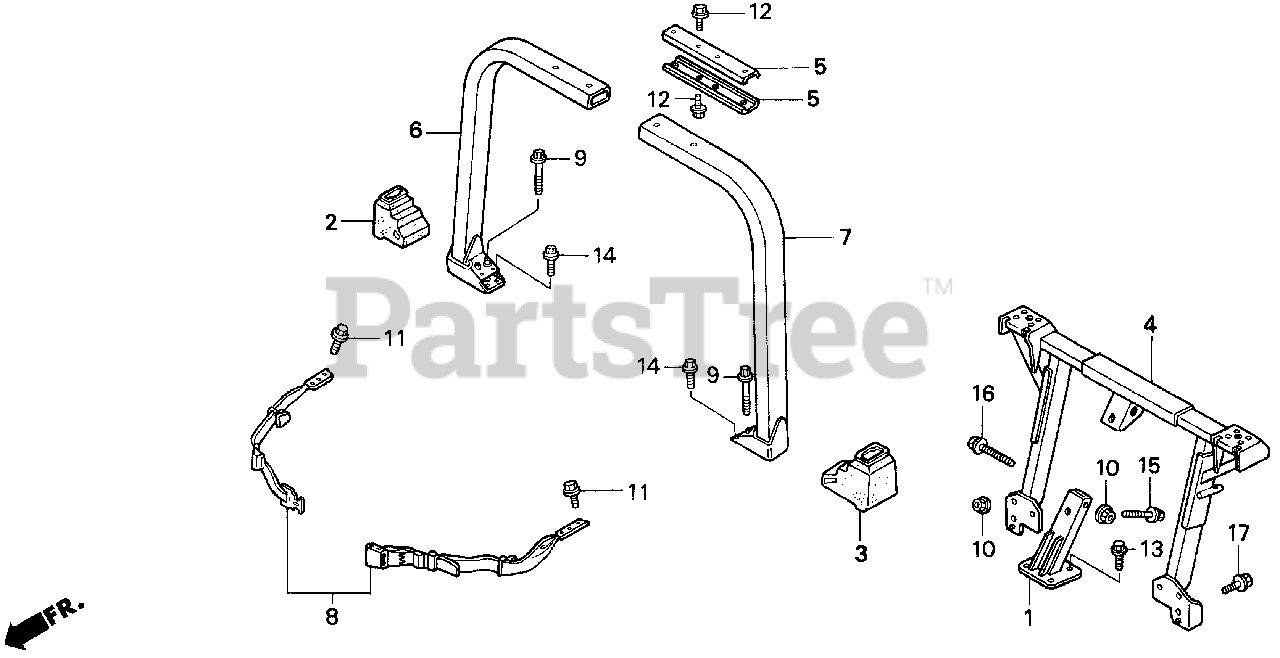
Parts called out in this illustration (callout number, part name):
1	FRAME, CENTER *NH247* (ASSEMBLY GRAY)
2	COVER, R. ROPS.
3	COVER, L. ROPS.
4	FRAME, ROPS. *NH247* (ASSEMBLY GRAY)
5	JOINT, ROPS.
6	PILLAR, R. ROPS. *R165* (JOLLY RED)
7	PILLAR, L. ROPS. *R165* (JOLLY RED)
8	SEAT BELT ASSY.
9	BOLT, FLANGE (10X87)
10	NUT, FLANGE (10MM)
11	BOLT, FLANGE (8X16)
12	BOLT, FLANGE (10X20)
13	BOLT, FLANGE (10X25)
14	BOLT, FLANGE (10X35)
15	BOLT, FLANGE (10X60)
16	BOLT, FLANGE (10X85)
17	BOLT, FLANGE (12X25)
